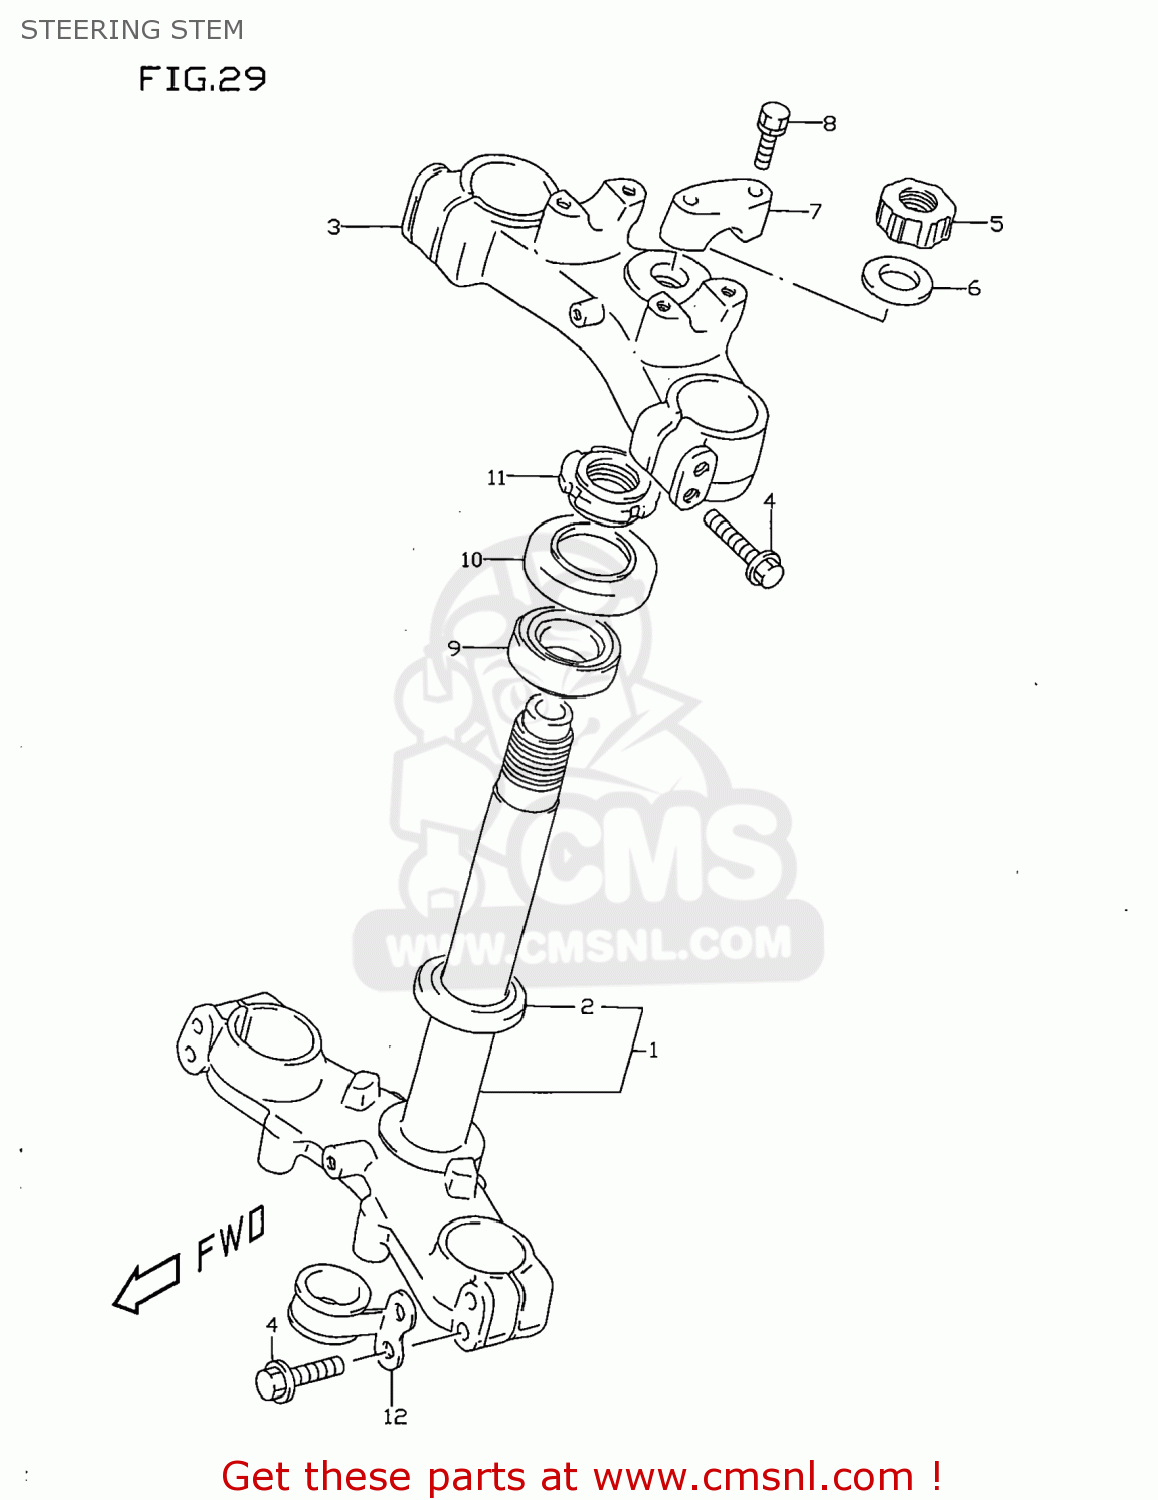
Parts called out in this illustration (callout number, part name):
1	STEM,STEERING
2	BEARING(26X47X15)
3	HEAD,STEERING STEM
4	BOLT
5	NUT
6	WASHER
7	HOLDER,HANDLEBAR
8	BOLT
9	TAPER,ROLLER BEARING
10	SEAL,STEERING UPR DUST
11	NUT,STEERING
12	CLIP
